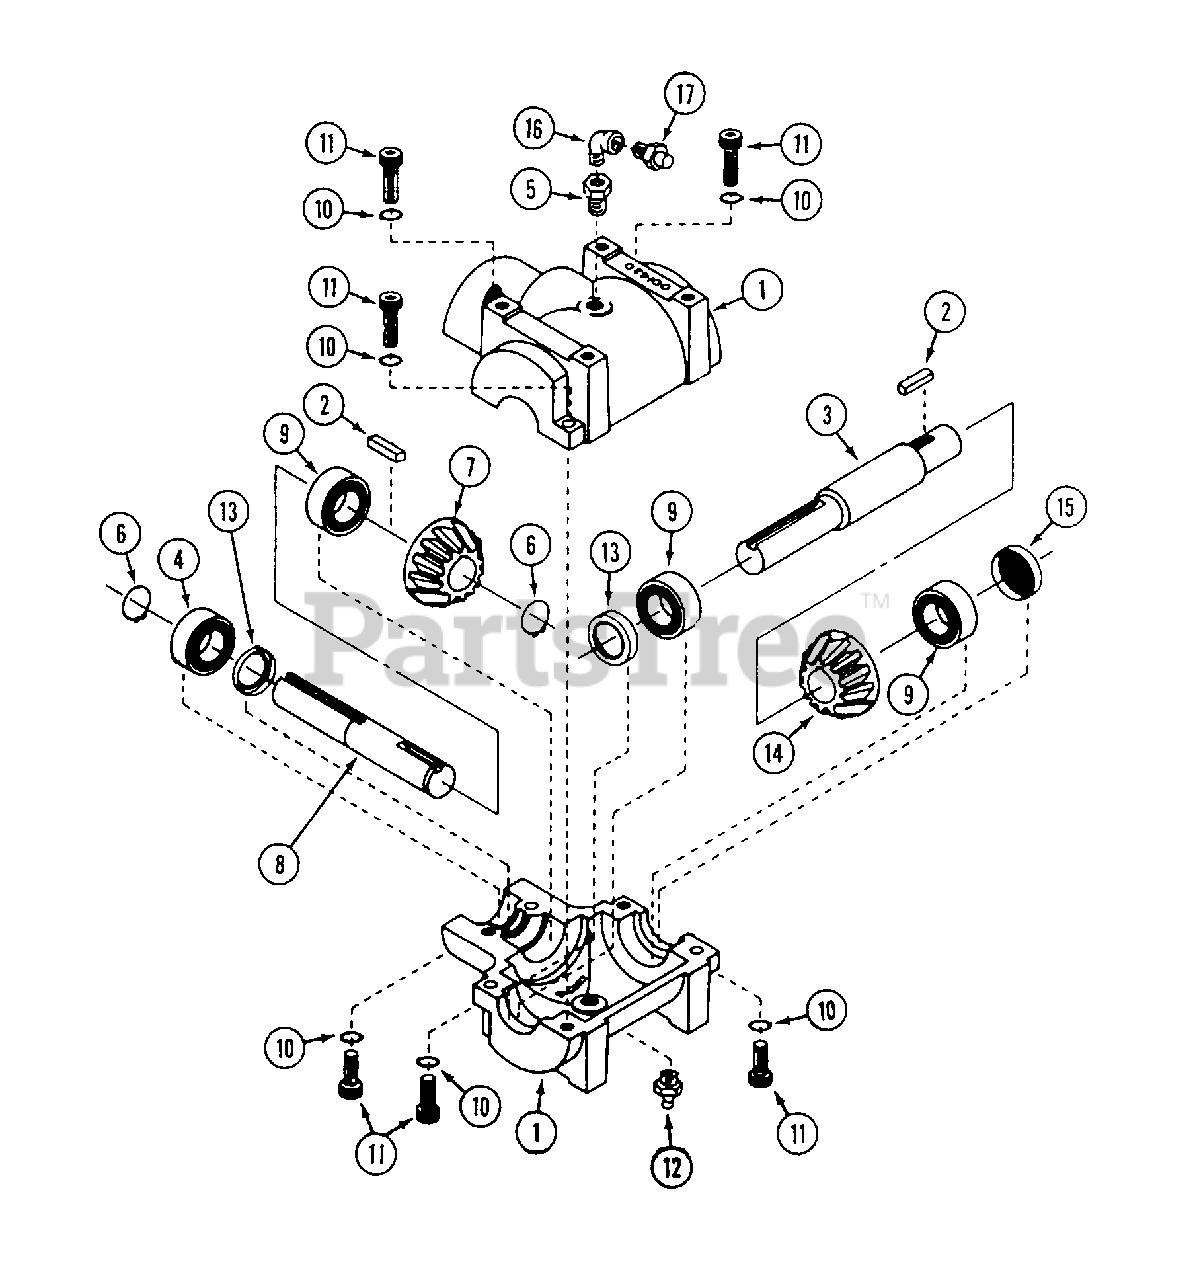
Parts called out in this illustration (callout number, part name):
1	HOUSING - half
2	KEY - 3/16" x 3/16" x 1"
4	BEARING - ball
5	BUSHING - pipe 1/4" x 1/8"
6	RING - retaining
7	GEAR - output shaft
8	SHAFT - output
9	BEARING - ball
10	LOCKWASHER
11	CAP SCREW - allen head
12	FITTING - grease 1/4" NPT
14	GEAR - input shaft
15	PLUG - expansion
16	ELBOW - street 1/8" x 90°.
17	VALVE - relief
